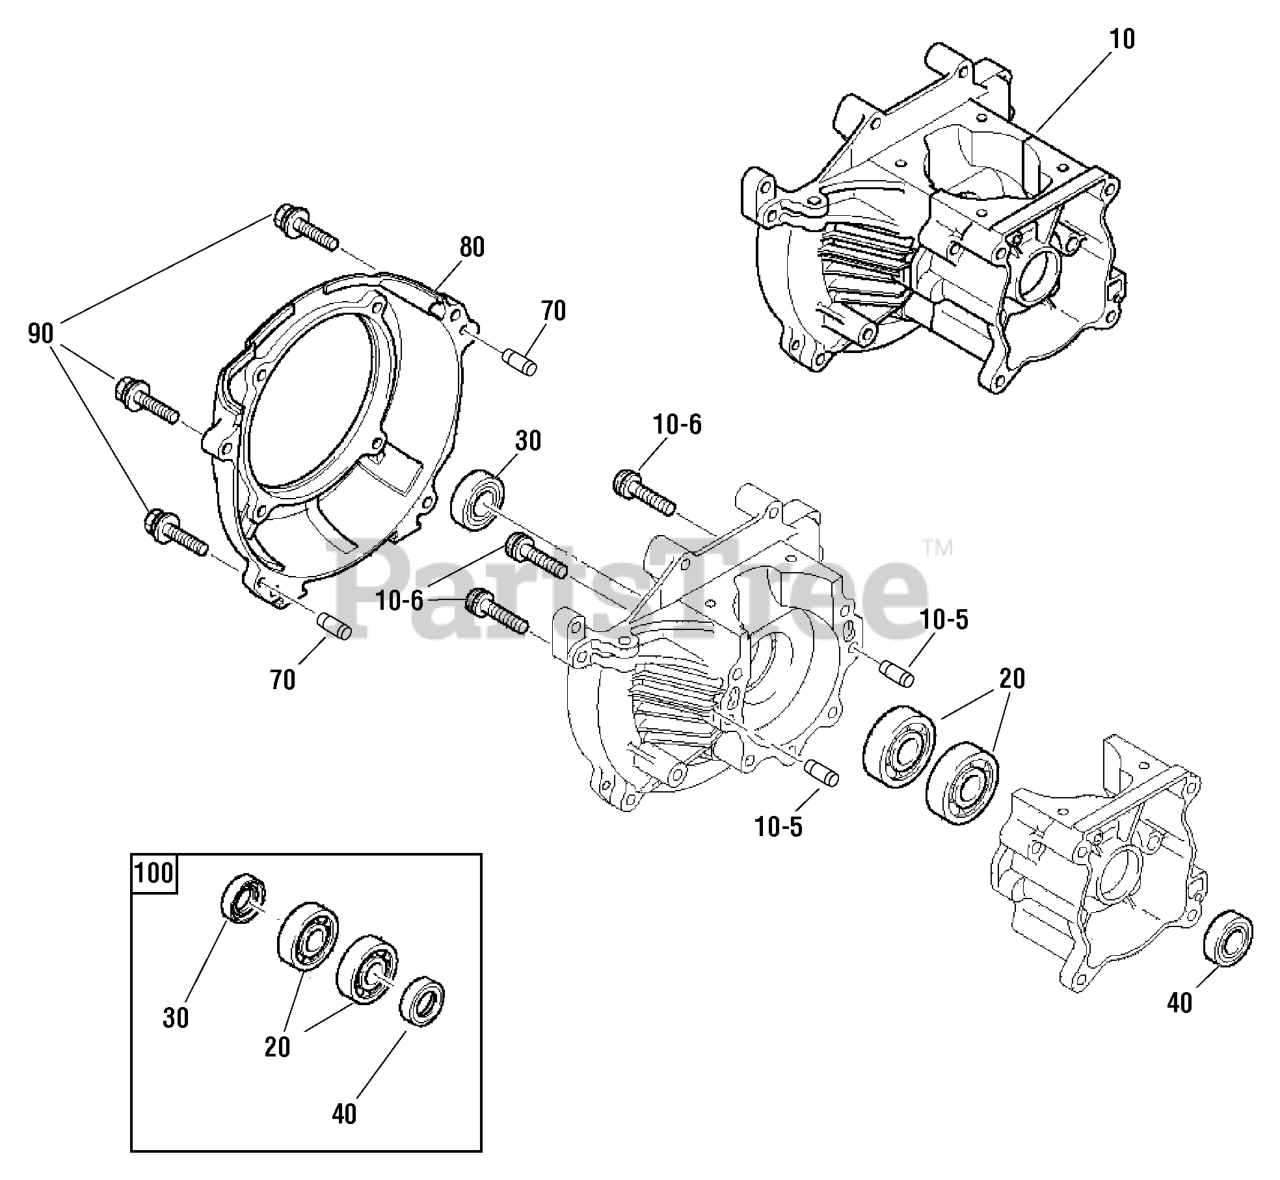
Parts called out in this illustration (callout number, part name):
10	CRANKCASE ASSEMBLY
10-5	PIN, Dowel
10-6	SCREW & WASHER
20	BEARING, Ball
30	OIL SEAL
40	OIL SEAL
70	PIN, Dowel
80	CASE, Fan
90	BOLT & WASHER
100	KIT, Bearing Seal & Gasket
